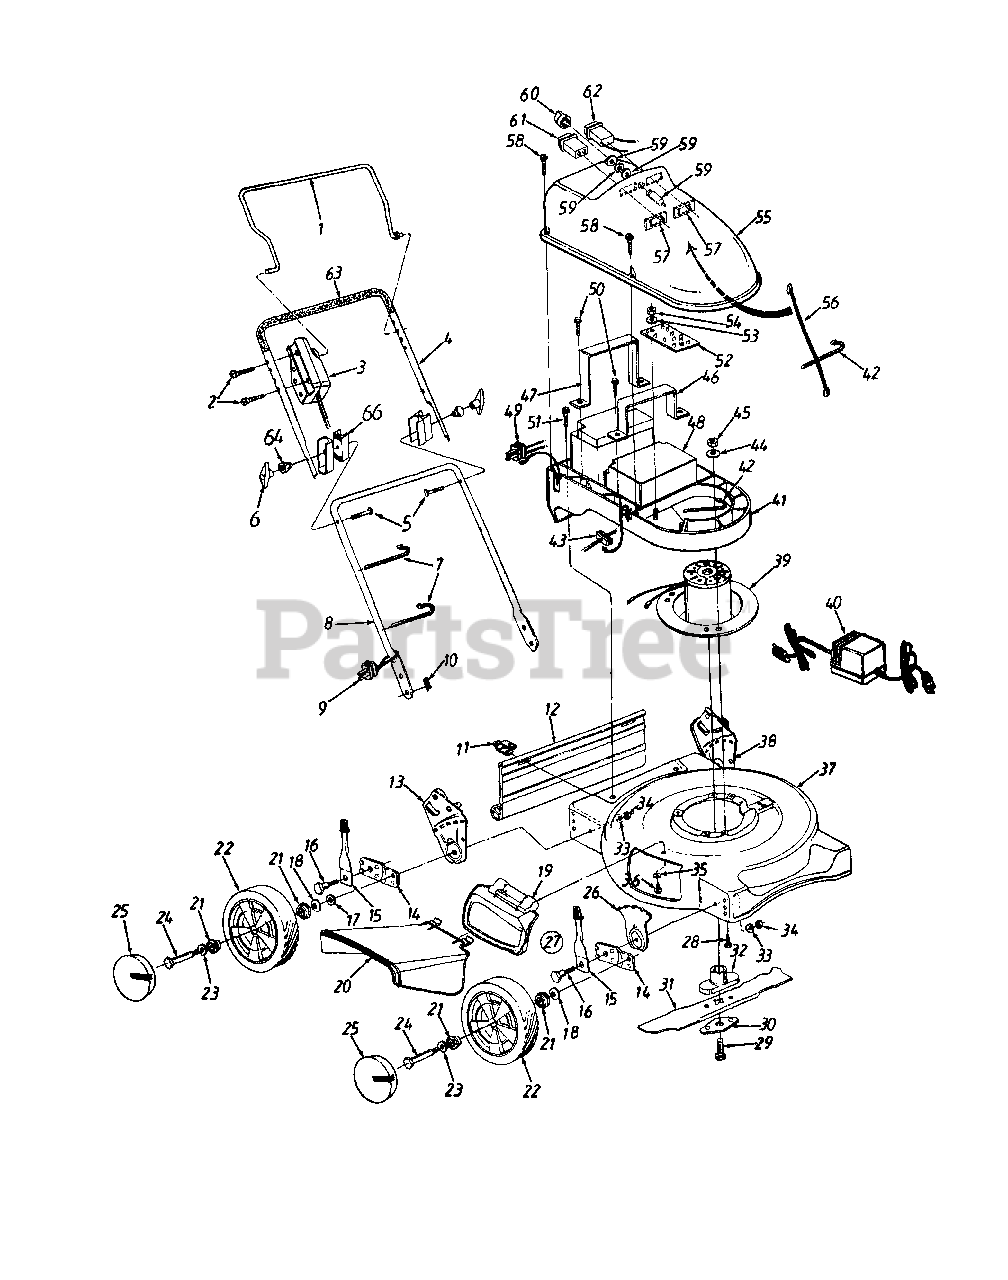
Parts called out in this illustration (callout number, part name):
3	Switch Assembly
6	Handle Knob
7	Cable Tie
9	Plug
10	Hairpin Clip
11	Hinge Clip
12	Rear Flap
13	Handle Bracket - R.H.
15	Spring Lever Assembly. w/Knob
16	Shld. Bolt .5" Dia. x .43" Lg.
17	Fl-Wash. .385" I.D. x 1" O.D.
18	Bell-Wash. .38" I.D. x .88" O.D.
19	Mulching Plug Assembly
20	Chute Deflector
21	Ball Bearing
22	Wheel Assembly.
23	Wave Wash. .51" I.D. x .75" O.D.
24	Shld. Bolt .498" Dia. x 1.45
25	Hub Cap
26	Height Adj. Plate
27	Height Adj. Ass'y. Comp. - R.H.
28	Hex Wash. Self-Tap Scr. 3/8-16 x 1"
29	Hex Bolt 3/8-24 x 2.5" Lg.
30	Blade Bell Support
31	18" Blade
32	Blade Adapter
33	Bell Washer .39 I.D. x 1.38" O.D.
34	Hex Nut 3/8-16 Thd.
35	Bell-Wash. 1/4" I.D.
36	Hex Wash. Hd. TT-Tap Scr. 1/4 x .5" Lg.
39	Motor Assy.
40	Charger
41	Tray Assy.
42	Cable Tie
43	Harness Assy. Switch
44	Flat Washer .406" I.D.
45	Push-on Spd. Nut 3/8 Thd.
46	Front Bracket Assembly.
47	Rear Bracket Assembly.
48	Battery Assembly.
49	Charger Plug
50	Hex Hd. Hi-Lo Scr. 1/4 x .75" Lg.
51	Hex Wash. Hd. TT-Tap Scr. 1/4-20 x 1"
52	Circuit Board
53	Fl-Wash. .21" I.D. x .56" O.D.
54	Palnut Self-Threading
55	Motor Cover
56	Key Switch Harness Assy.
57	Mounting Clamp
58	Hex AB-Tap Scr.#10 x .75" Lg.
59	Key Switch
61	Meter
62	Meter
63	Foam Grip
64	Insulator Knob
66	Upper Handle Insulator
